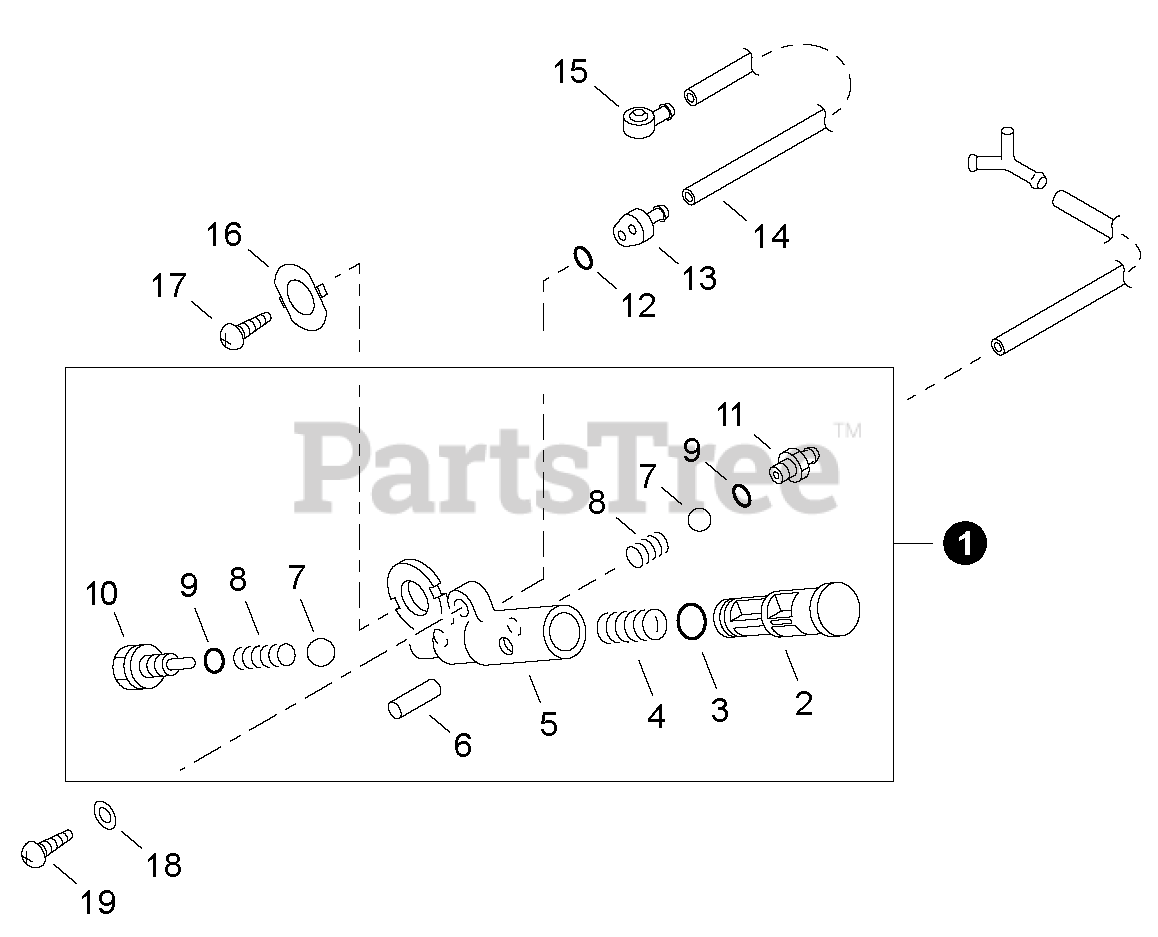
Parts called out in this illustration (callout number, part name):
1	OIL PUMP ASSY - ORANGE
2	PISTON, OIL PUMP - ORANGE
3	O-RING 7 MM
5	BODY, OIL PUMP
6	PIN, SPRING 2×16
7	VALVE, BALL
8	SPRING, COMPRESSION
10	ADAPTOR, OIL PUMP
11	CONNECTOR, PIPE
12	O-RING 3
13	CONNECTOR, PIPE
14	PIPE 3×6×125 BLACK
15	CONNECTOR, PIPE
16	BRACKET, OIL PUMP
17	SCREW 4×10
18	WASHER 5.5×12×0.8
19	SCREW 5×20
